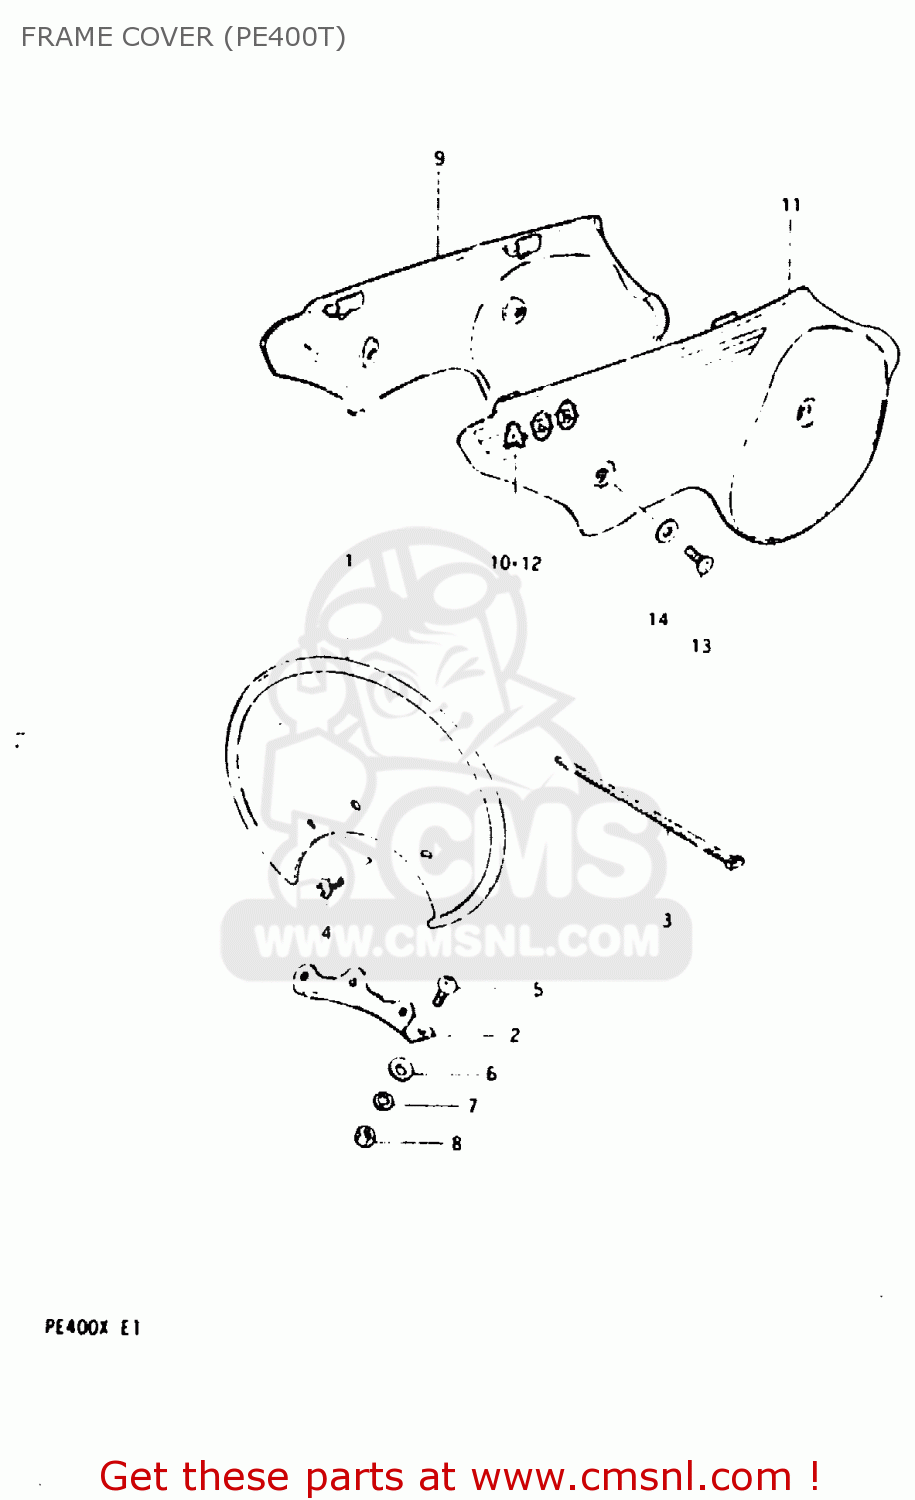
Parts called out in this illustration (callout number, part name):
1	PLATE,NUMBER,FRONT
2	BRACKET
3	CLAMP
4	SCREW
5	SCREW
6	WASHER
7	LOCK WASHER
8	NUT
9	COVER,FRAME,R(YELLOW)
10	TAPE,FRAME COVER,RIGHT
11	COVER,FRAME,L(YELLOW)
12	TAPE,FRAME COVER,LEFT
13	SCREW 6X12
14	WASHER
